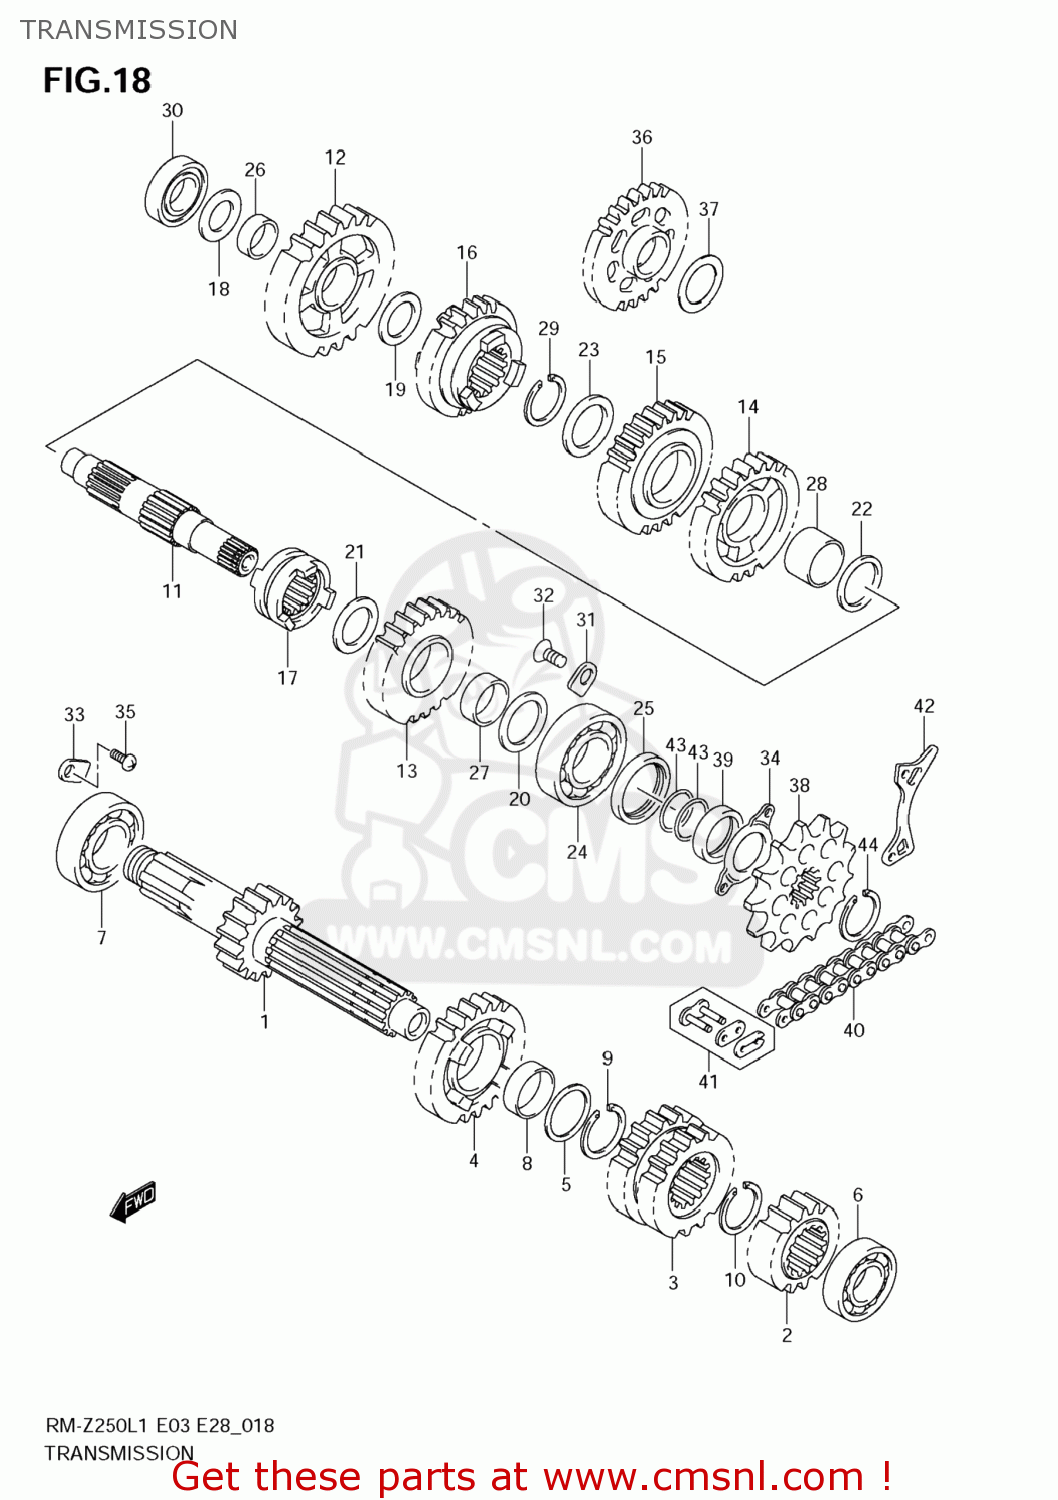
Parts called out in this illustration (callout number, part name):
1	SHAFT,COUNTER
2	GEAR,2ND DRIVE
3	GEAR,3RD & 4TH DRIVE
4	GEAR,5TH DRIVE(NT:22)
5	SHIM(24X29X1)
6	BEARING(17X40X9.5)
7	BEARING(22X50X14)
8	BUSH(24X27X0.0)
9	CIRCLIP
10	CIRCLIP
11	SHAFT,DRIVE
12	GEAR,1ST DRIVEN(NT:28)
13	GEAR,2ND DRIVEN
14	GEAR,3RD DRIVEN(NT:25)
15	GEAR,4TH DRIVEN(NT:26)
16	GEAR,5TH DRIVEN(NT24)
17	DOG,SLIDING
18	SHIM(17X28X1)
19	SHIM(20X28X1)
20	WASHER,2ND DRIVEN GEARL
21	SHIM(22X30X1)
22	SHIM(24X30X1)
23	SHIM(24X30X1)
24	BEARING(20X52X7.5)
25	SEAL,OIL(28X38X7.5)
26	BUSH(20X24X10)
27	BUSH(22X25X12)
28	BUSH(24X27X18)
29	CIRCLIP
30	BEARING(17X40X12)
31	RETAINER,COUNTER BEARING,R
32	SCREW(6X12)
33	RETAINER
34	RETAINER,DRIVE SHAFT OIL SEAL
35	BOLT(6X12)
36	GEAR,KICK STARTER IDLE
37	WASHER,KICK IDLE
38	SPROCKET,ENGINE
39	SPACER,ENGINE SPROCKET
40	CHAIN,DRIVE
41	JOINT SET
42	PLATE,FR CHAIN GUIDE
43	O RING(D:1.9,ID:19.8)
44	CIRCLIP
